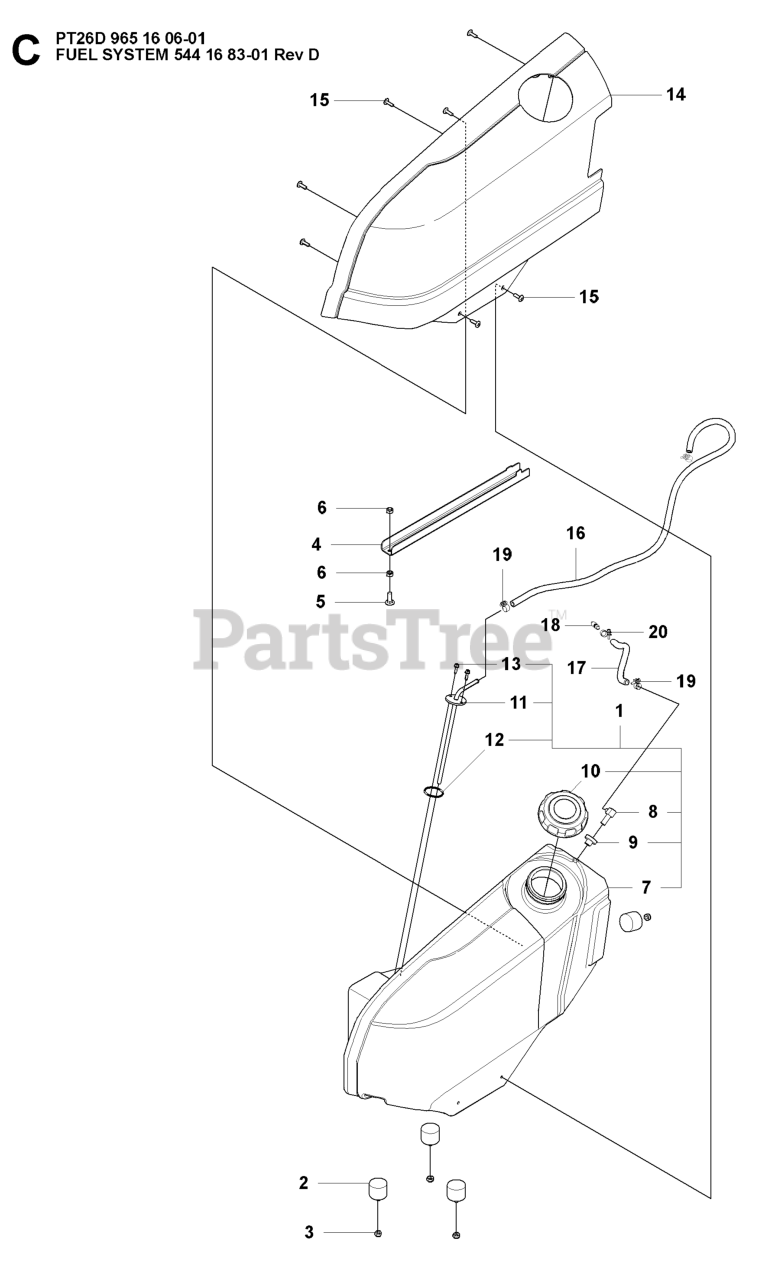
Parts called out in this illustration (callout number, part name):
1	FUEL TANK ASSY
2	ANTIVIBRATION ELEMENT
3	LOCKNUT M8
6	LOCKNUT M8
9	RUBBER GROMMET
10	TANK CAP - DIESEL
11	CONNECTION FUEL TANK
14	TANK COVER FUEL TANK
19	RP HOSE CLAMP FUEL HOSE
20	HOSE CLAMP FUEL HOSE
